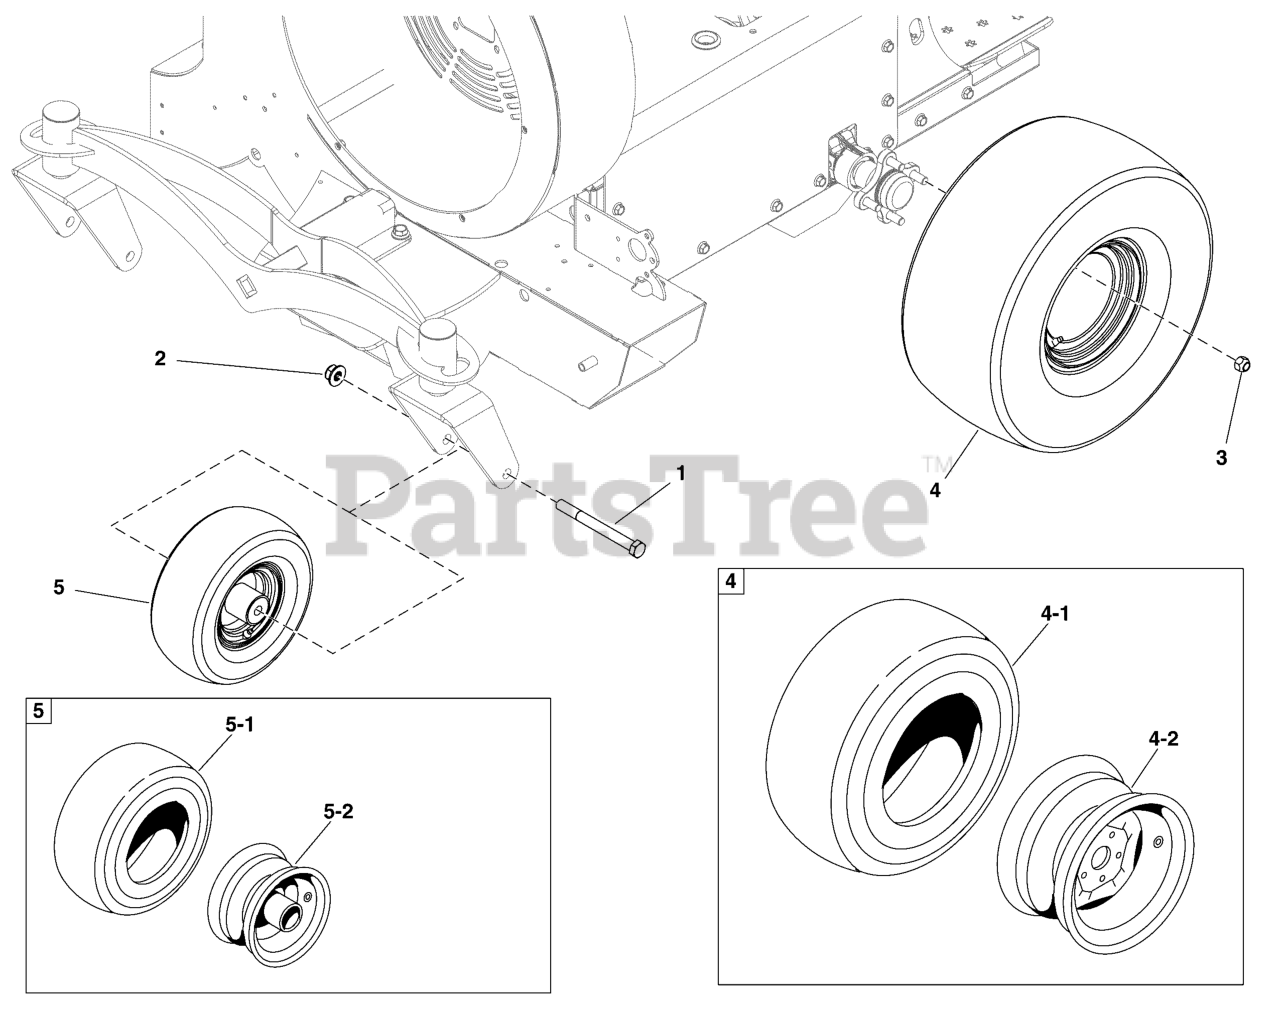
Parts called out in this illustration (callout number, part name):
1	BOLT, 5/8-11 X 6-1/2, CZ
2	NUT, 5/8-11 HEX NYLOCK FLANGE
3	NUT, 1/2-20, FOR WHEEL BOLT SILVER
4	TIRE/WHEEL ASM, 20 X 8.00-8, TURF
4-1	TIRE, 20-8 x 8 4PLY (TIRE ONLY)
4-2	WHEEL, 8 X 6.125 BW, 4 ON 4BC, RIM ONLY
5	TIRE ASSEMBLY, 11 X 4.00 - 5
5-1	TIRE, 11-4 X 5, 4PLY, TIRE ONLY
5-2	WHEEL, RIM
5-3	5/8 X 1-3/8 DOUBLE SEALED FLANGED BB
